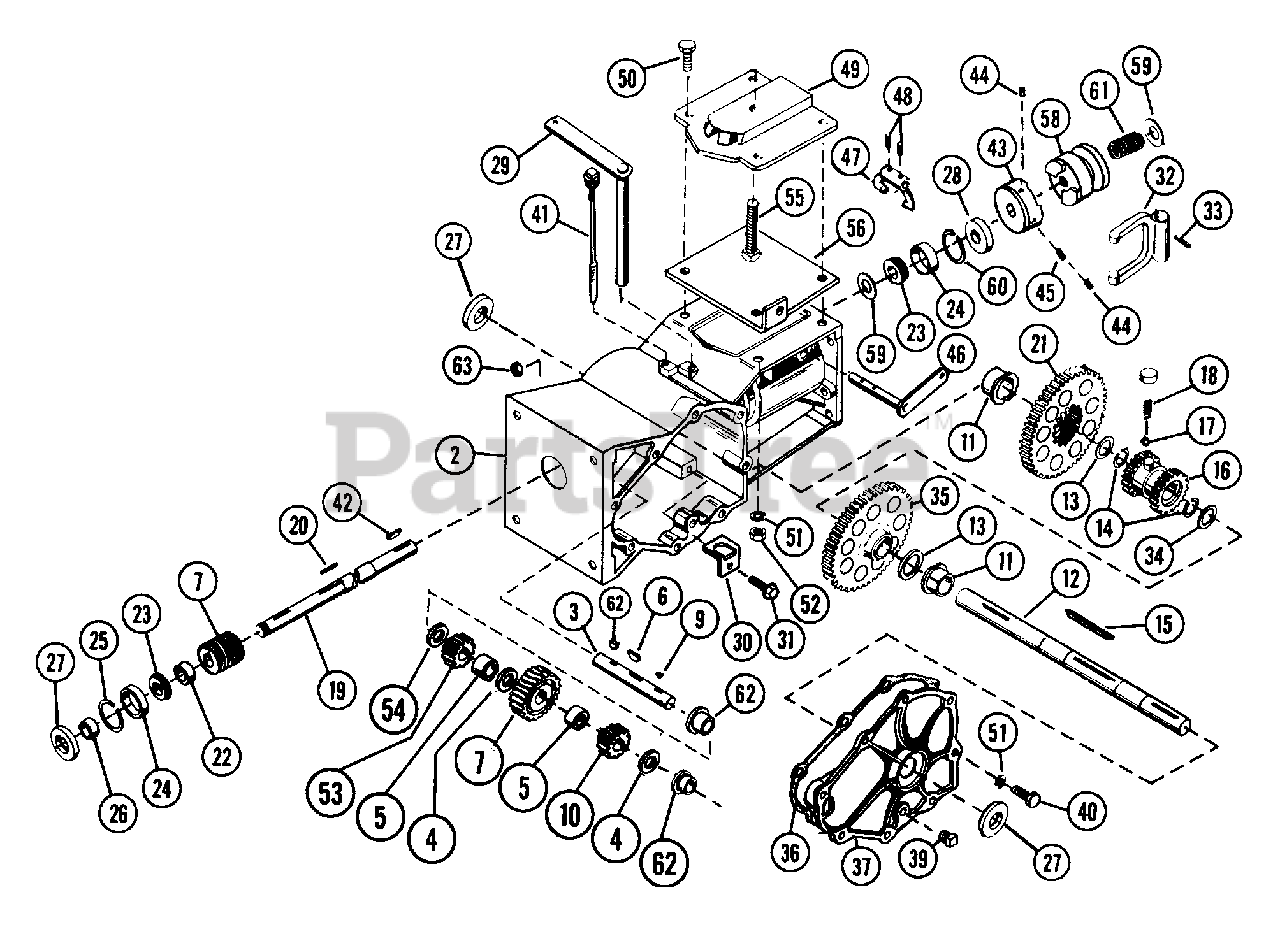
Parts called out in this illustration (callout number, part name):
1	TRANSMISSION GEARCASE ASSEMBLY
2	TRANSMISSION HOUSING
3	SHAFT, PINION
4	WSHR-HDND-THRST .758X1.23X.031
5	SPACER 1.25 X .75 X .75
6	MANUAL, OWNERS-P/S PWR-HD-AR H
7	WORM AND WORM GEAR
9	KEY-WDRF .188X.75X.313 SAE 9
10	LOW PINION
11	BSHG-FLG 1.000X1.25X1.000X1.50
12	AXLE SHAFT
13	WSHR-HRD-THRS 1.007X1.542X.062
14	RG-RTNG-EXT 1.00X.078
15	KEY-FTHR .25X2.75X.25 SAE1035
16	CLUTCH HUB
17	STEEL BALL
18	SG-COMP .047X.31X.593 WLD11
19	WORM SHAFT
20	KEY-SQ .188X1.0X.188 SAE 8630
21	HIGH GEAR ASSEMBLY
23	BRG-CONE .750X.61
24	BRG-CUP 1.781X.475
25	SNAP RING KIT
26	SPACER BUSHING .99 X .75 X .50
27	SEAL 1.000X1.785X.250
28	SEAL .750X1.781X.250
29	HIGH-LOW SHIFT LEVER
30	RETAINER CLIP
31	SCR-FLG-WHZ 10-24X.75 PL
32	SHIFT YOKE
33	PIN-ROLL .250X1.00
35	LOW GEAR
37	TRANSMISSION COVER
39	PIPE PLUG
40	BLT-HEX .31-18X1.00 PL GR 2
41	DIP STICK
42	KEY-FTHR .188X1.25X.187 SAE
43	TILLER DRIVING JAW
44	SCR-SET .32-18X.38 SKHCUPNL OH
45	WMT, ZOOM FRAME
46	TINE ENGAGING FORK SHAFT
47	CLUTCH FORK
48	PIN-ROLL .188X1.00
49	PIVOT CAP
50	BLT-HEX .31-18X1.25 PL GR2
51	WSHR-LK .312X.097 PL HVY
52	NUT-HEX .312-18
53	HIGH PINION
54	WSHR-HDND-THRST .758X1.23X.031
55	SWIVEL BOLT
56	PIVOT BRACKET
58	TILLER JAW CLUTCH
59	WSHR-FL-STL .755X1.375X.125
60	RG-RTNG-INT 1.781X.052
61	SG-COMP .080X.97X2.18 WLD14
62	KEY-WDRF .188X.625X.31 SAE9MOD
